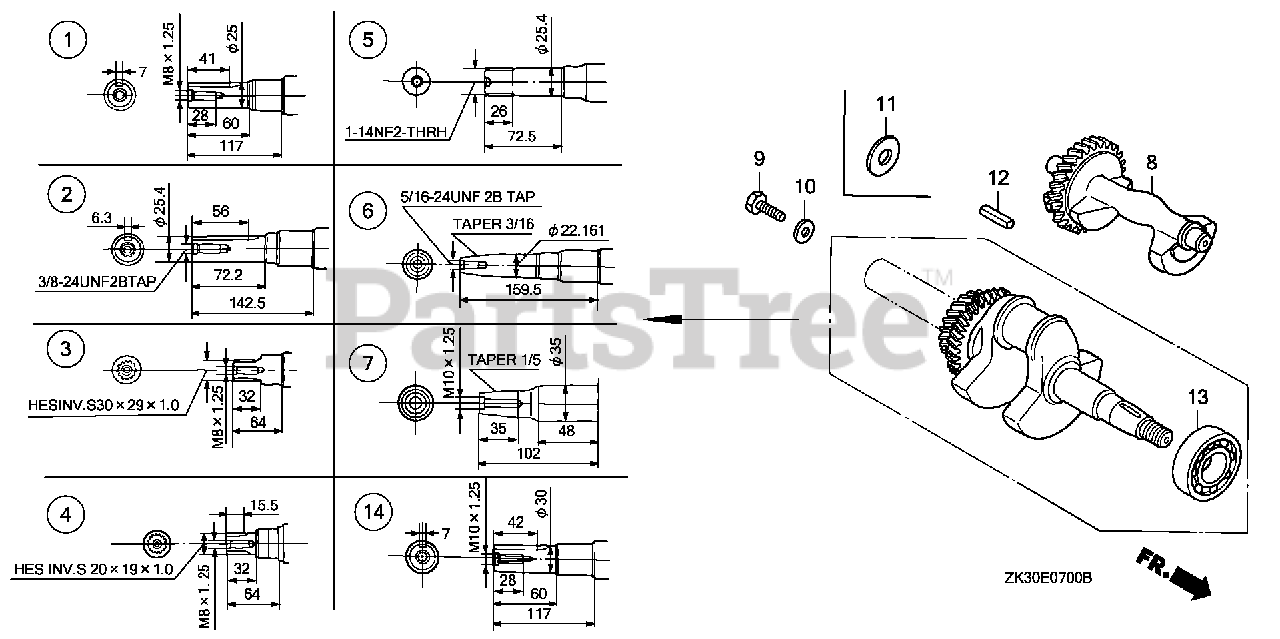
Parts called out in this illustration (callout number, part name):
6	CRANKSHAFT
8	WEIGHT, BALANCER
13	BEARING, RADIAL BALL (6207)
